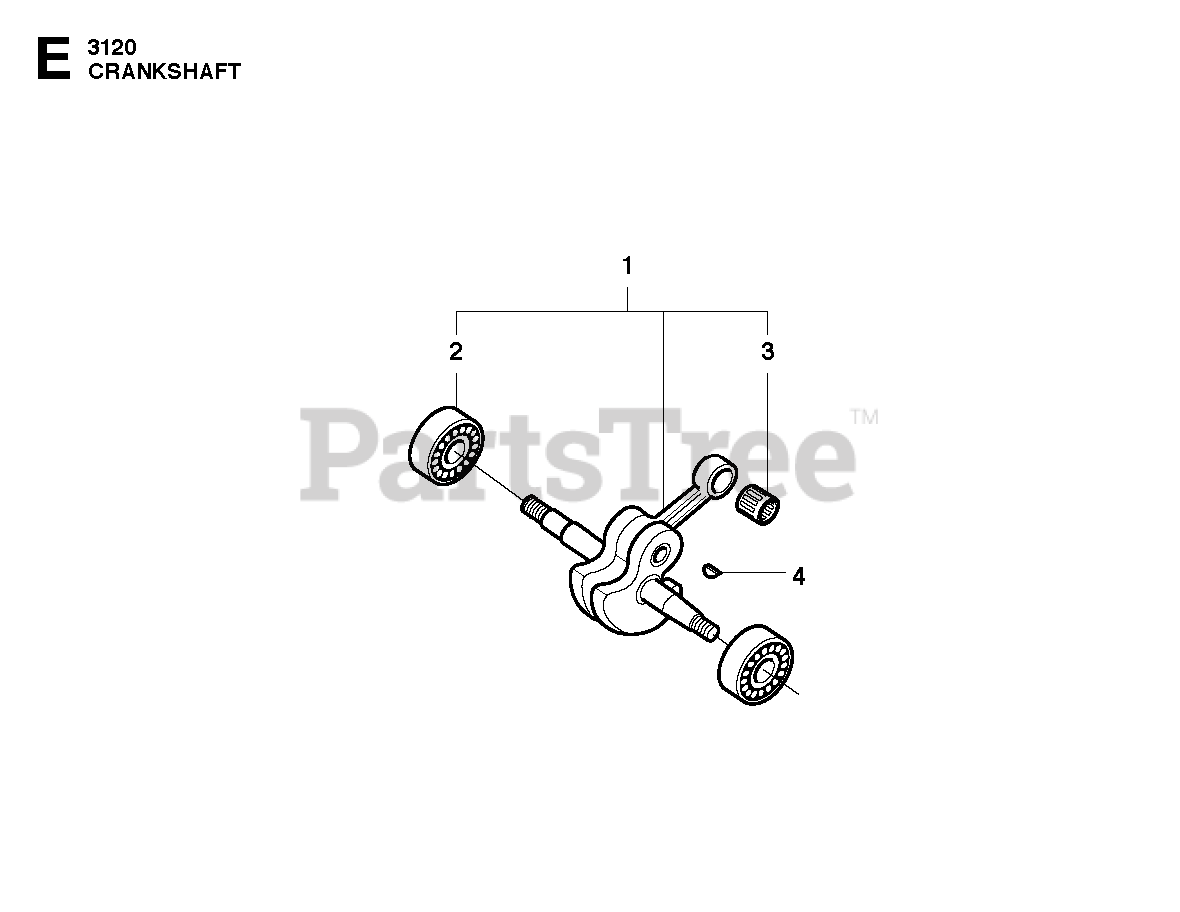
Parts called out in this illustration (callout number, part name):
1	Crankshafts
2	BALL BEARING 6203C3QE6
3	SUPPORT BUSHING
4	WOODRUFF KEY
